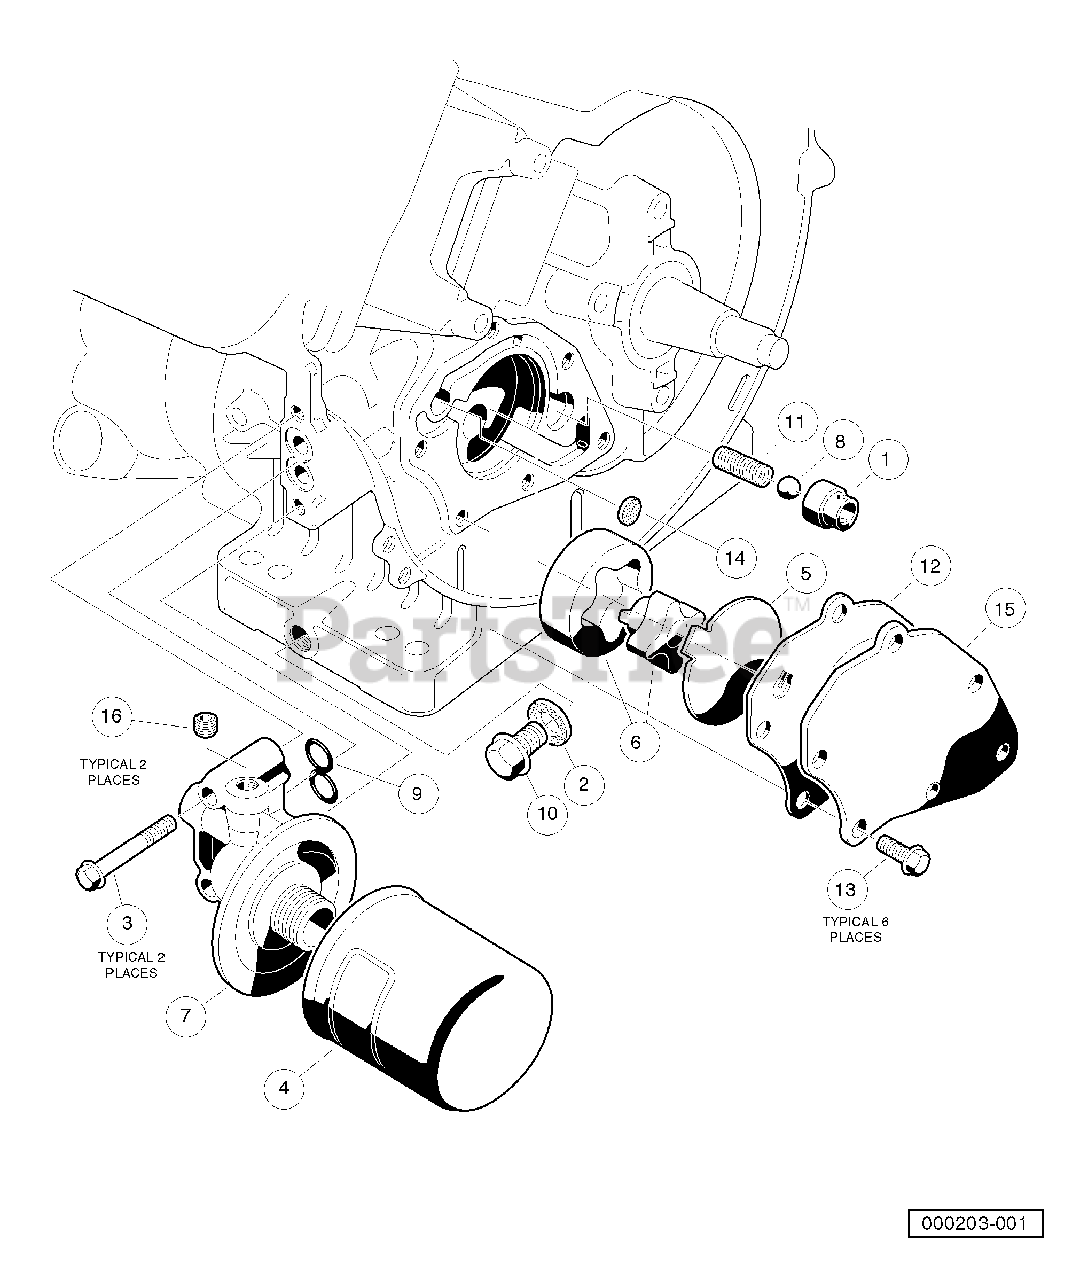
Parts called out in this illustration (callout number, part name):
1	Seat, Value Oil Press Relief
2	Gasket, Drain Plug
3	Bolt, Flange Head
4	Filter, Oil
5	Plate, Oil Pump
6	Oil Pump And Rotor
7	Bracket, Oil Filter Mount
8	Ball, Steel, Press, Relief
10	Plug, Drain
13	Bolt, Flanged
15	Cover, Pump
